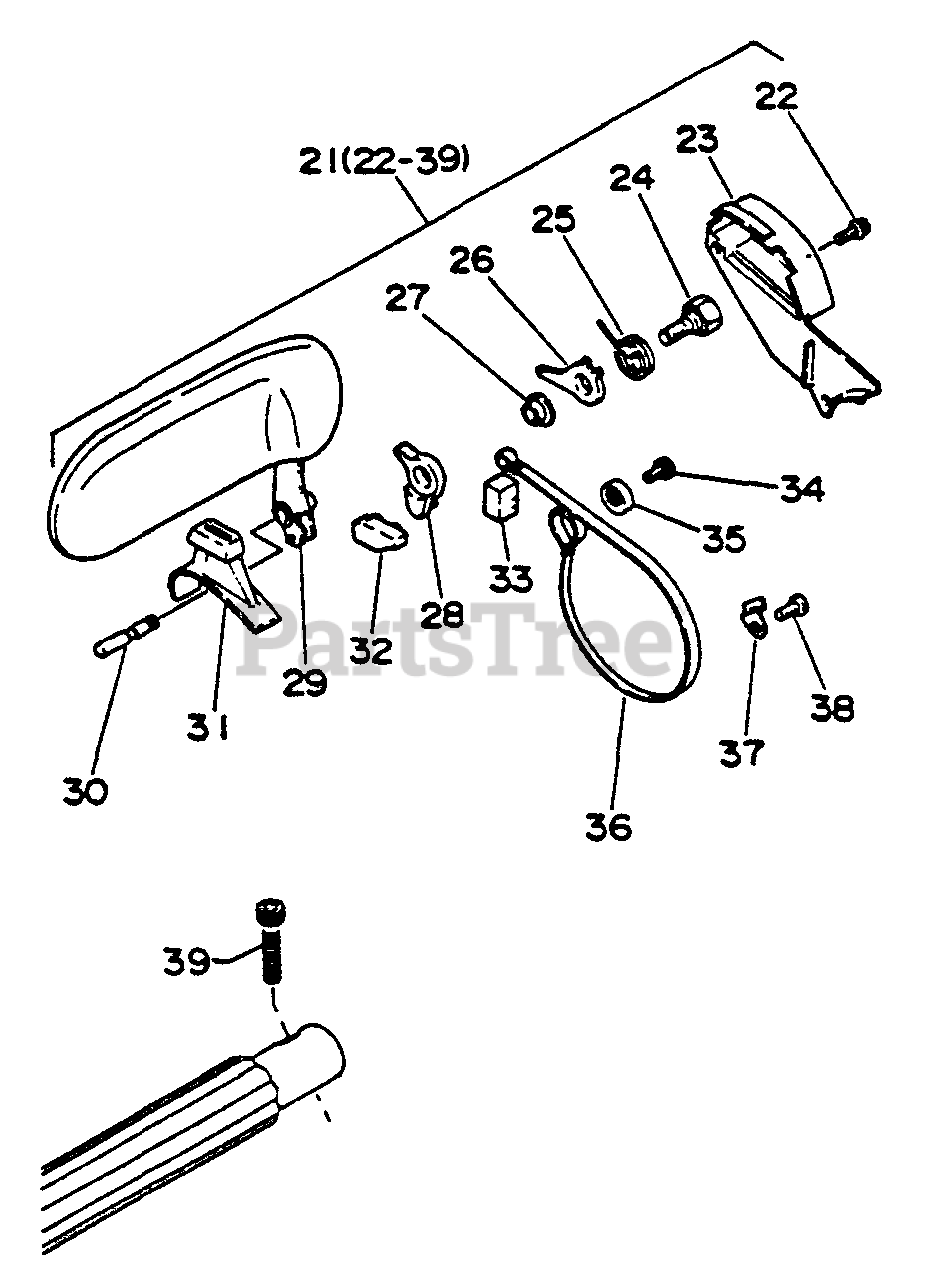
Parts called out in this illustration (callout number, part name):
21	CHAIN BRAKE ASSY
22	SCREW - 4X10
23	COVER, BRAKE
25	SPRING, RETURN
28	CONNECTOR
29	HANDLE
31	COVER, BRAKE
32	RESET, BRAKE
33	SEAL
34	SCREW - 5X10
35	ADJUSTER, BRAKE BAND
36	BAND, BRAKE
37	RETAINER, BRAKE BAND
38	SCREW - 5X10
39	SCREW - 5X30
